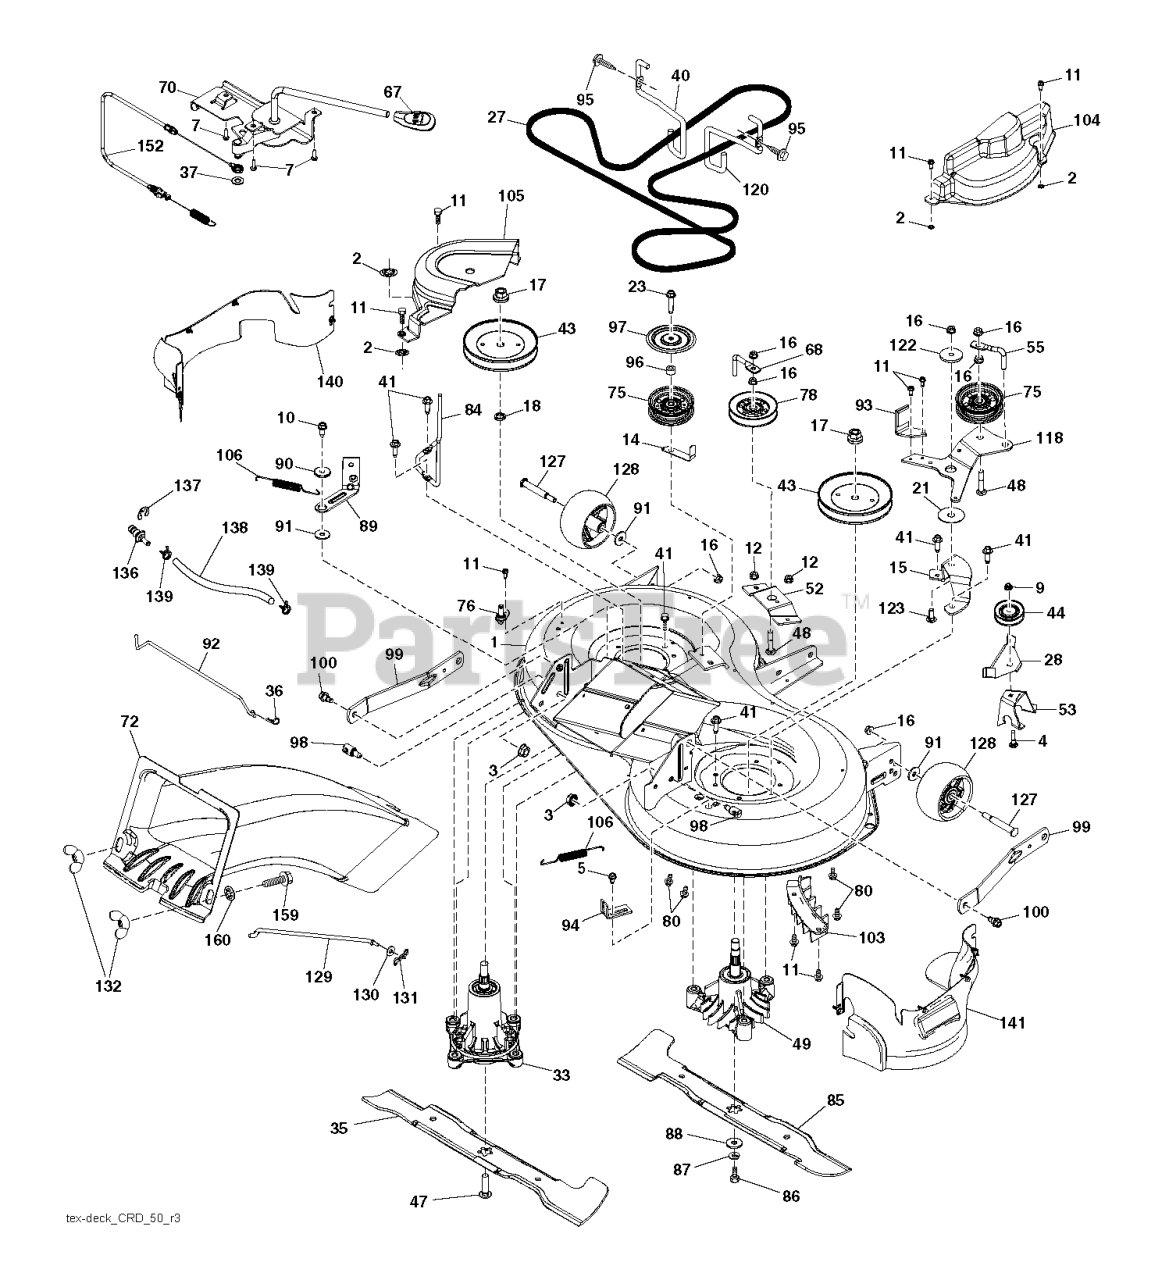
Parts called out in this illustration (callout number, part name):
1	KIT.SVC.DECK.WLD.97CM.TEX.498
2	PALNUT 1/4
4	BOLT.CARRIAGE.5/16-18
5	BOLT.5/16HEX.WHS.HD
9	NUT HEX FLG NYLOCK BLK 5_16-1
10	SCREW 3/8-16X1
11	SCREW.1/4-20X5/8
12	NUT HEXAGON FLANGE 5/16-18 ST
14	KEEPER, BELT IDLER
15	BRACKET CRD IDLER ARM MOUNT BL
16	NUT LOCK FLG 3/8-16 UNC
18	WASHER.SPACER.MANDREL
23	BOLT;HEX_3/8-16 X 1.78.CLRZINC
27	BELT CRD DECK DRIVE
28	KEEPER 97 CRD ANGLED IDLER KEE
33	KIT.MANDREL.NONGREASE.TALL
35	BLADE.3N1.LH.CRD.97
36	RETAINER M
37	WASHER PLAIN WASHER 3/8 X 0.08
40	KEEPER BELT ENGINE LH
41	BOLT.HEX.WASHR.HED.313-18X1.19
43	PULLEY.MANDREL.5.438.PD
44	PULLEY.V-IDLER.
47	SCREW.SEMS.7/16-20X1.HEX.HEAD
49	MANDREL ASM.CRD RH 6PT STAR
53	BRACKET 97 CRD ANGLED V-IDLER
67	HANDLE.CLUTCH.CABLE.LT
70	CLUTCH.ASM.MANUAL.LT.PRED
72	CHUTE.TEX.CRD.GEN I.97 UPPER
76	1/2" BARB.DECK.WASHOUT.PORT
78	REPL BY 532 1467-63
80	GSPW Bolts
84	KEEPER.BLT.PNT.MNDRL.PULL.6.25
85	BLADE.3N1.RH.CRD.97
86	BOLT.3/8-24X1.25GR8. LHTHRD
88	WASHER.BLADE
89	ARM.BRAKE.97.LH
90	SPACER.RETAINER
92	LINK 97 CRD MANUAL DRIVE BRAKE
93	BRAKE CRD RH BRAKE ARM BLACK E
94	BRKT.CLUTCH.CABLE
95	SCREW, 3/8-16X3/4
96	SPACER
97	PROTECTOR
98	STUD.W/"D"ANTI-ROTATION
99	ARM.SUSPENSION.MOWER.R
100	BOLT.SHOULDER
103	GUARD GUARD FRONT VENT
104	GUARD 97CRD RH MANDREL COVER;
105	MANDREL MANDREL COVER LH
106	SPRING.BRAKE.RETURN.38"
120	KEEPER BELT RH
122	SPACER.RETAINER.MOWER
128	WHEEL.GAUGE.RALLY
129	ROD.ANTI.SWAY.48/54"K4
131	PIN.COTTER.5/16.BOW TI
132	KNOB.HANDLE.3/8.TRI-POINT.BLAC
136	PLUG WASHOUT PORT HOOKUP
138	HOSE.3/8ID.BULK.12"
140	GUARD.ASSEMBLY.97.LH.FRENCH
141	GUARD.ASSEMBLY.97.RH.FRENCH
152	CABLE CABLE CLUTCH MANUAL W/S
